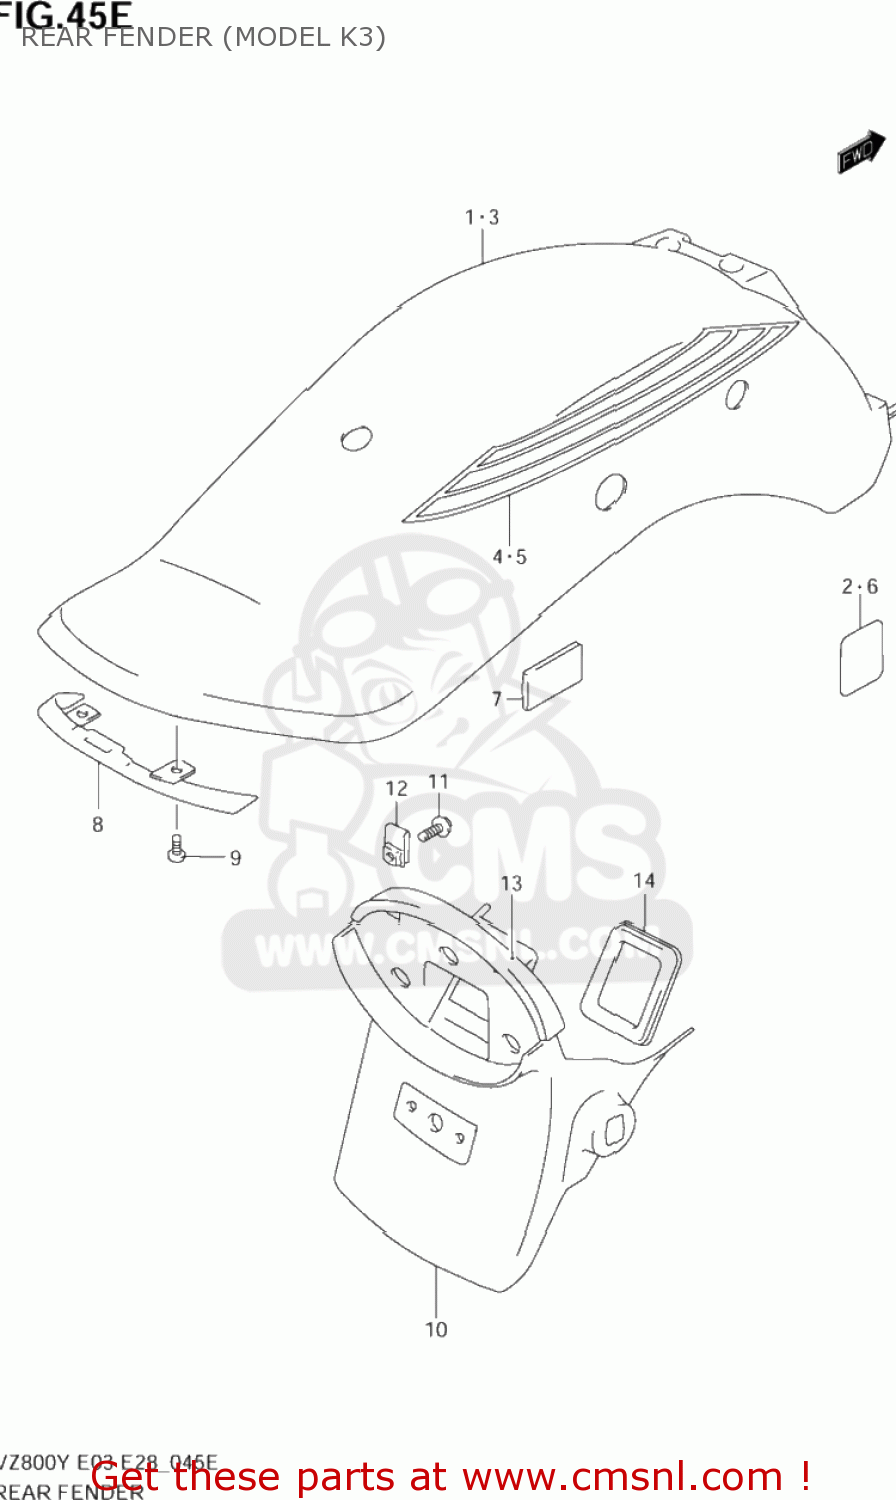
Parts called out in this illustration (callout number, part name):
1	FENDER,RR
2	PAD
3	FENDER, REAR (SILVER)
4	TAPE,RR FENDER,R
5	TAPE,RR FENDER,L
6	PAD
7	CUSHION
8	COVER,RR FENDER RR
9	SCREW
10	EXTENSION,RR FENDER
11	SCREW
12	PLATE,FRAME COVER
13	CUSHION,RR FENDER EXTENSION
14	CAP,RR FENDER EXTENSION
